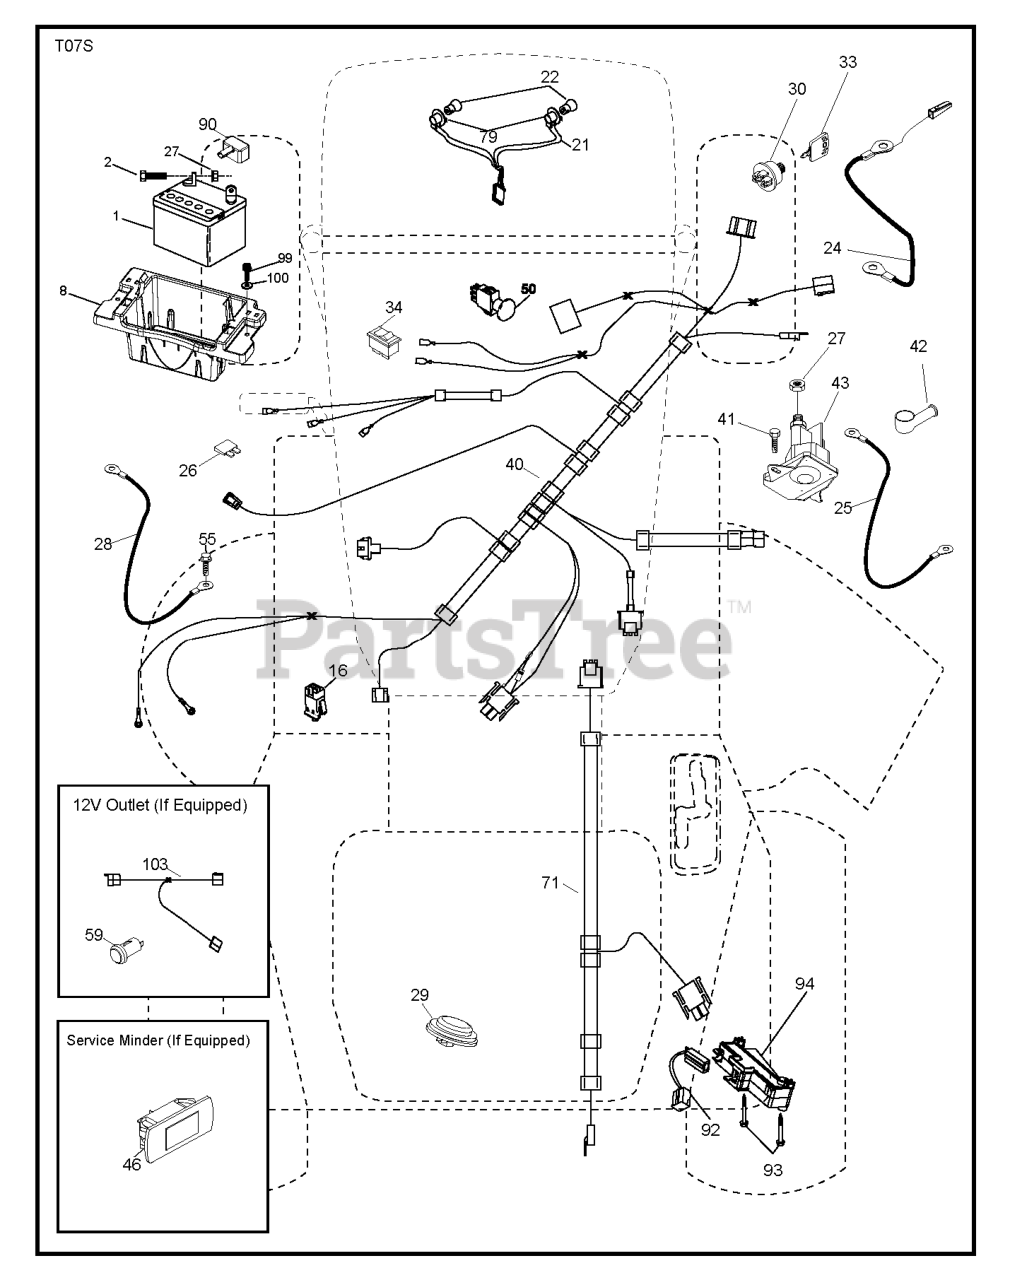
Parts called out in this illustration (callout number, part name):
1	Battery 12 Volt 25 Amp
2	BOLT.HEX.1/4.X.3/4.DICHROMATE
8	TRAY.BATTERY BOX.FRONT
16	SWITCH INTERLOOK PUSH-IN
21	HARNESS.LIGHT W/4152J BULBS
24	CABLE.FRBATT.W/WIRE.8GA.8
25	CABLE.STARTER.8GA.17.5
26	FUSE 20AMP
27	NUT
28	CABLE.GROUND.21"BLK.8GA.90T
29	SWITCH.SEAT.DELTA.OPC.
30	SWITCH.IGN.DELTA.W.LGH.ROS
33	KEY.CHAIN.BLISTER.PACK.GEN.USA
40	HARNESS.IGN.DASH.HUQ/P
41	SCREW
42	TERMINAL COVER
43	SOLENOID.STARTER.BRASS.PLUNGER
46	GUAGE.SRVCMNDR.HRMTR.
50	SWITCH.PTO.8TERMINAL.STD.BLK
55	SCREW 5/16"
59	OUTLET.12-VOLT
71	HARNESS-CHASSIS SUB
79	BULB HOLDER ASM.
90	COVER.TERMINAL.BATTERY
92	HARNESS.PIGTAIL.CONSLE
93	SCREW.PLASTITE
94	MODULE.REVERSE.ROS
99	SCREW HEXWSHR 1/4-20X3/4
103	HARNESS PIGTAIL 12V OUTLET
